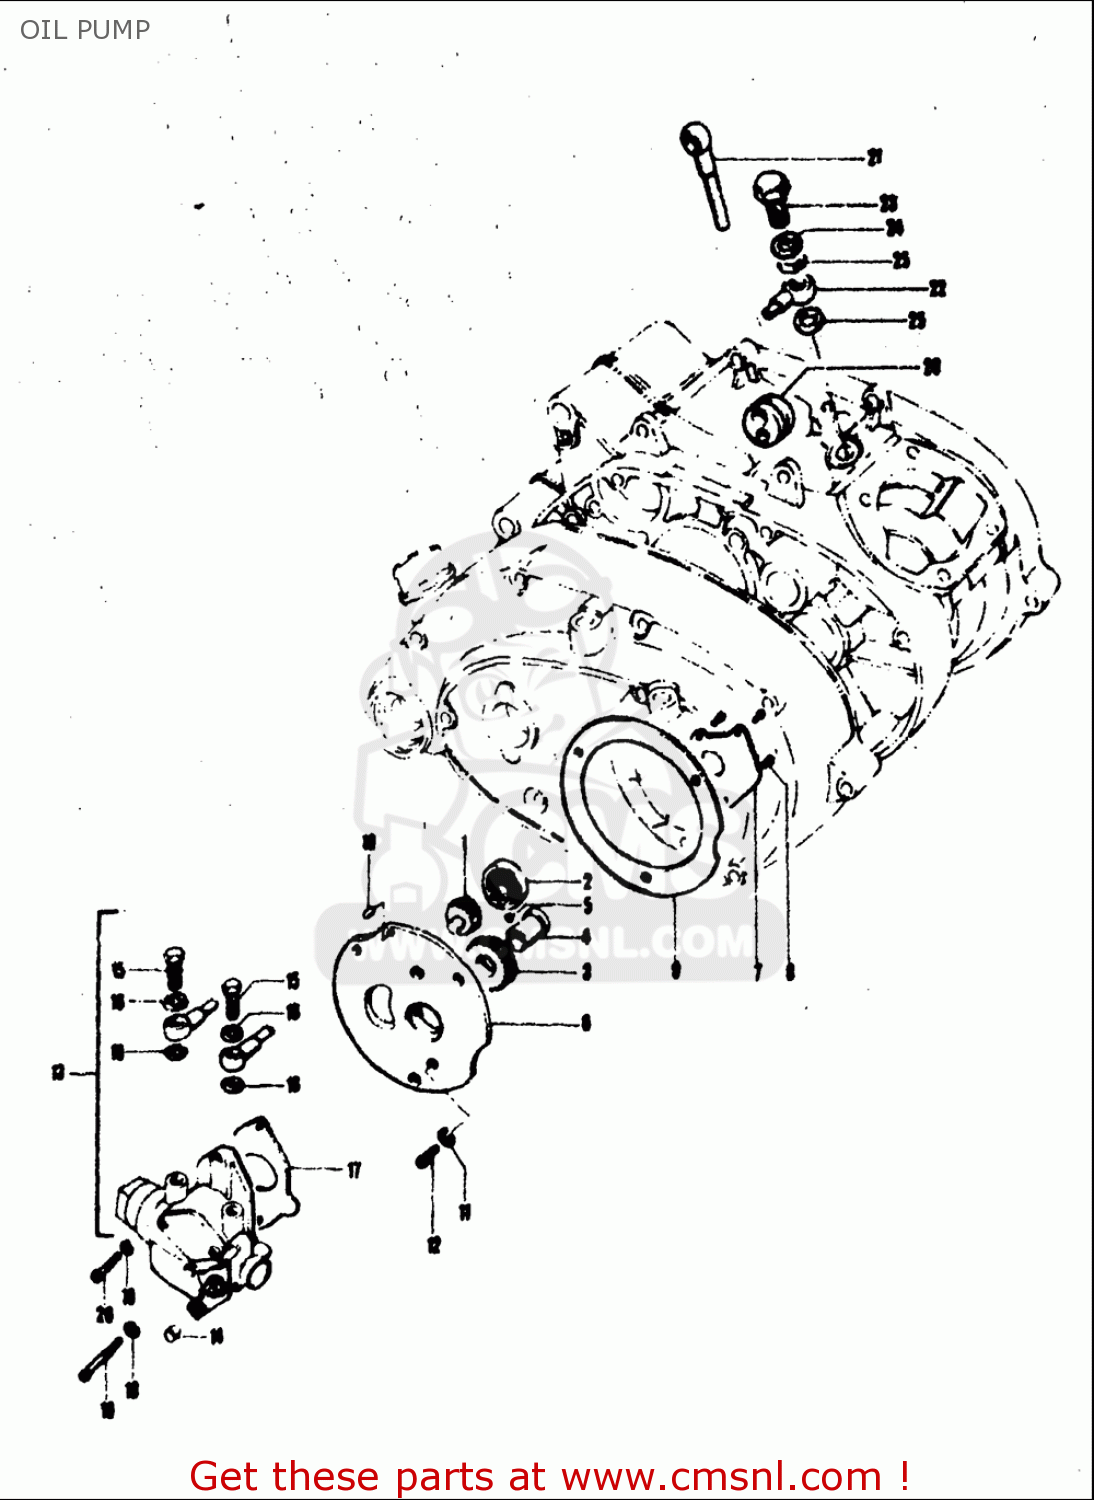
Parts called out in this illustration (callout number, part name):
5	PIN(2X5.5)
7	PLATE,OIL PUMP GEAR BOX
8	SCREW
9	GASKET,OIL PUMP GEAR CASE
10	PIN
11	WASHER,LOCK
12	SCREW(5X27)
14	TERMINAL,CABLE
15	UNION
16	GASKET(6.2X11X1).2 (NAS)
17	GASKET,OIL PUMP (NAS)
18	WASHER,LOCK
19	SCREW
22	HOSE
24	O RING(D:1.3,ID:7.6)
25	GASKET(10.5X14X1) (NAS)
26	GROMMET,OIL HOSE
